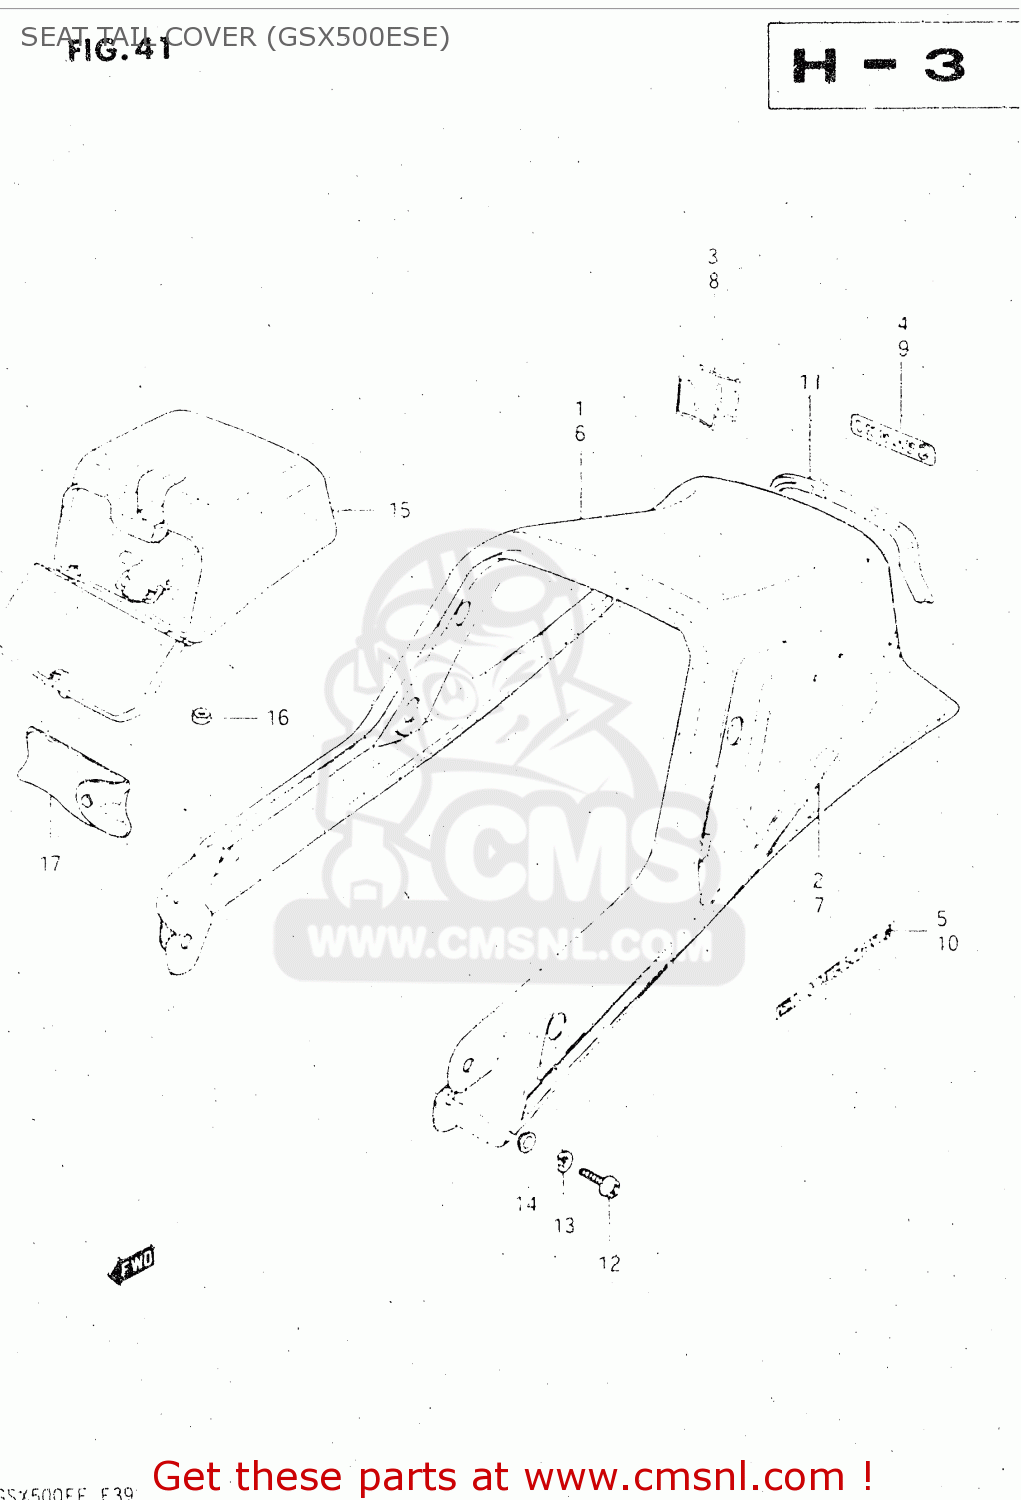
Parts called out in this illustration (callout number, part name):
1	TAIL COVER, SEAT
2	TAPE SET,SEAT TAIL COVER
3	EMBLEM, "S" MARK
4	EMBLEM
5	EMBLEM
6	TAIL COVER, SEAT
7	TAPE SET, SEAT TAIL COVER
8	EMBLEM, "S" MARK
9	EMBLEM
10	EMBLEM
11	BLIND,SEAT TAIL COVER
12	SCREW
13	LOCK WASHER
14	WASHER
15	BOX,SEAT TAIL
16	NUT
17	TOOL ASSY
